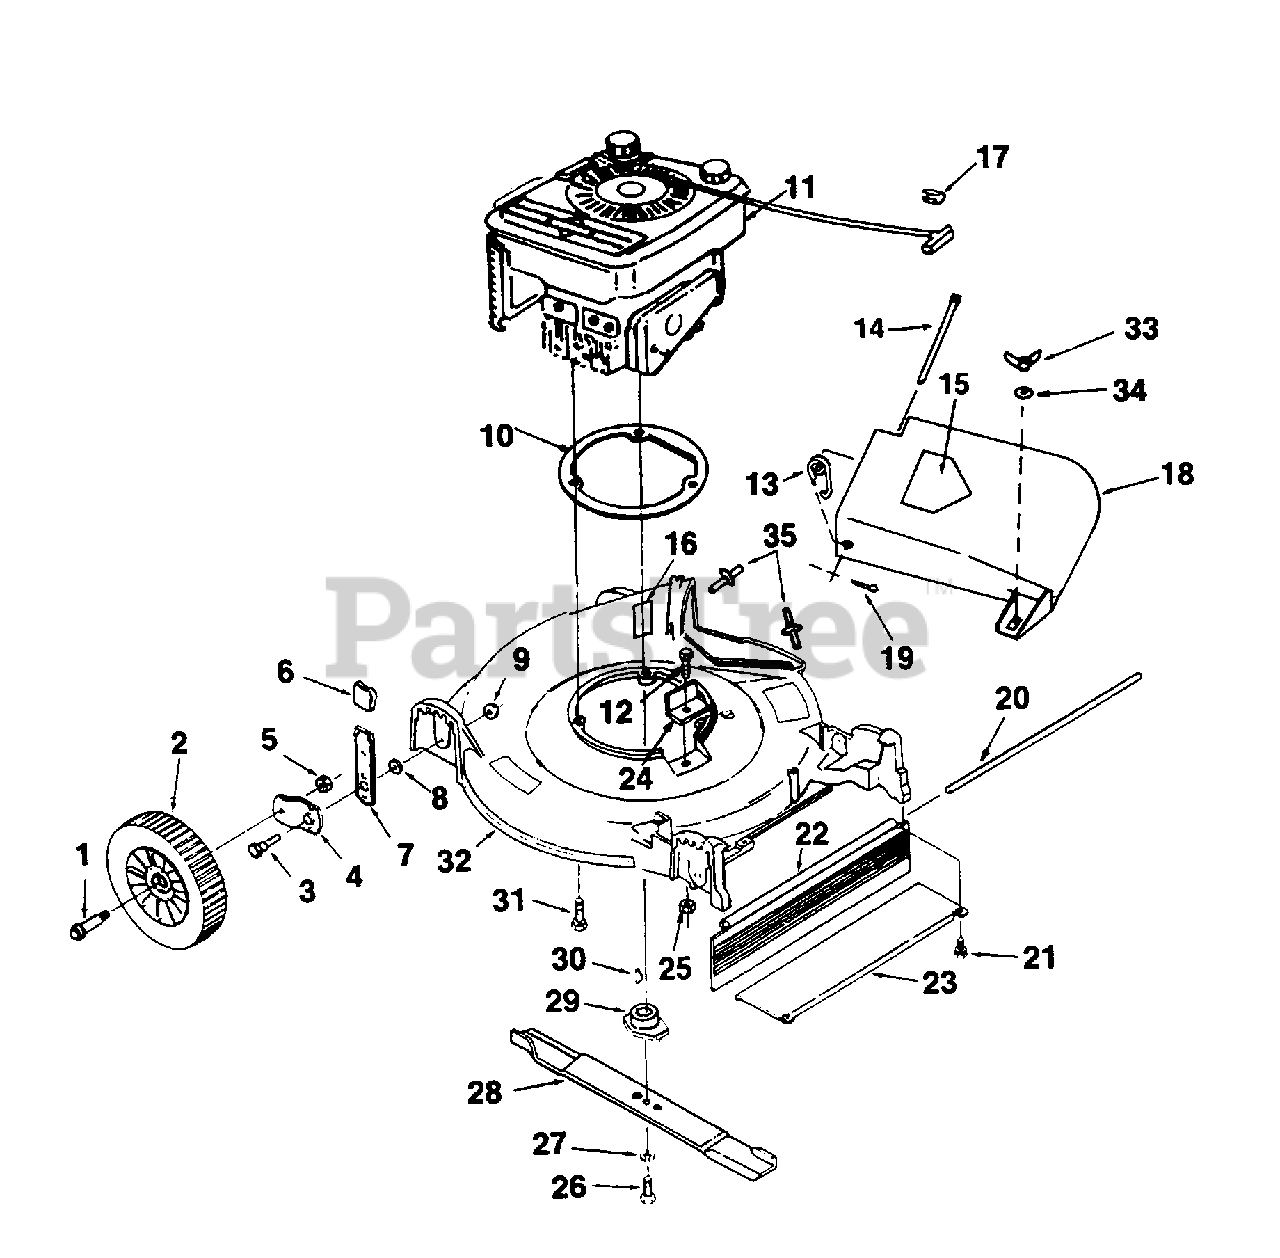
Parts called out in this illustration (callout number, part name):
1	BOLT- Axle (3/8-16)
2	WHEEL & TIRE
3	BOLT- Hex hd. (5/16-18)
4	ARM- Wheel adjusting
5	NUT- Hex (3/8-16)
6	KNOB
7	INDEXING SPRING & PIN ASSY.
9	NUT- Flange (5/16-18)
10	RING- Engine
11	ENGINE- 2 Cycle 4 H.P.
12	SCREW- Hex hd. (1/4-20 x 1/2")
14	PIN- Hinge
15	LABEL- Warning
16	DECAL- Gasohol
17	STOP- Rope
18	COVER- Discharge
19	PIN- Cotter (3/32 x 3/4")
20	ROD- Drag flap
21	SCREW- Hex hd. (1/4-20 x 3/4")
22	FLAP- Drag
23	COVER- Rear
24	COVER- Belt opening
25	NUT- Hex lock (1/4-20)
26	SCREW- Hex hd. (3/8-24 x 1 1/4")
27	WASHER- Lock (3/8")
28	BLADE
29	ADAPTOR- Blade
30	KEY- Woodruff
31	SCREW- Hex hd. (3/8-16 x 1 1/2")
32	DECK- Push
33	NUT- Wing
34	WASHER- Flat
